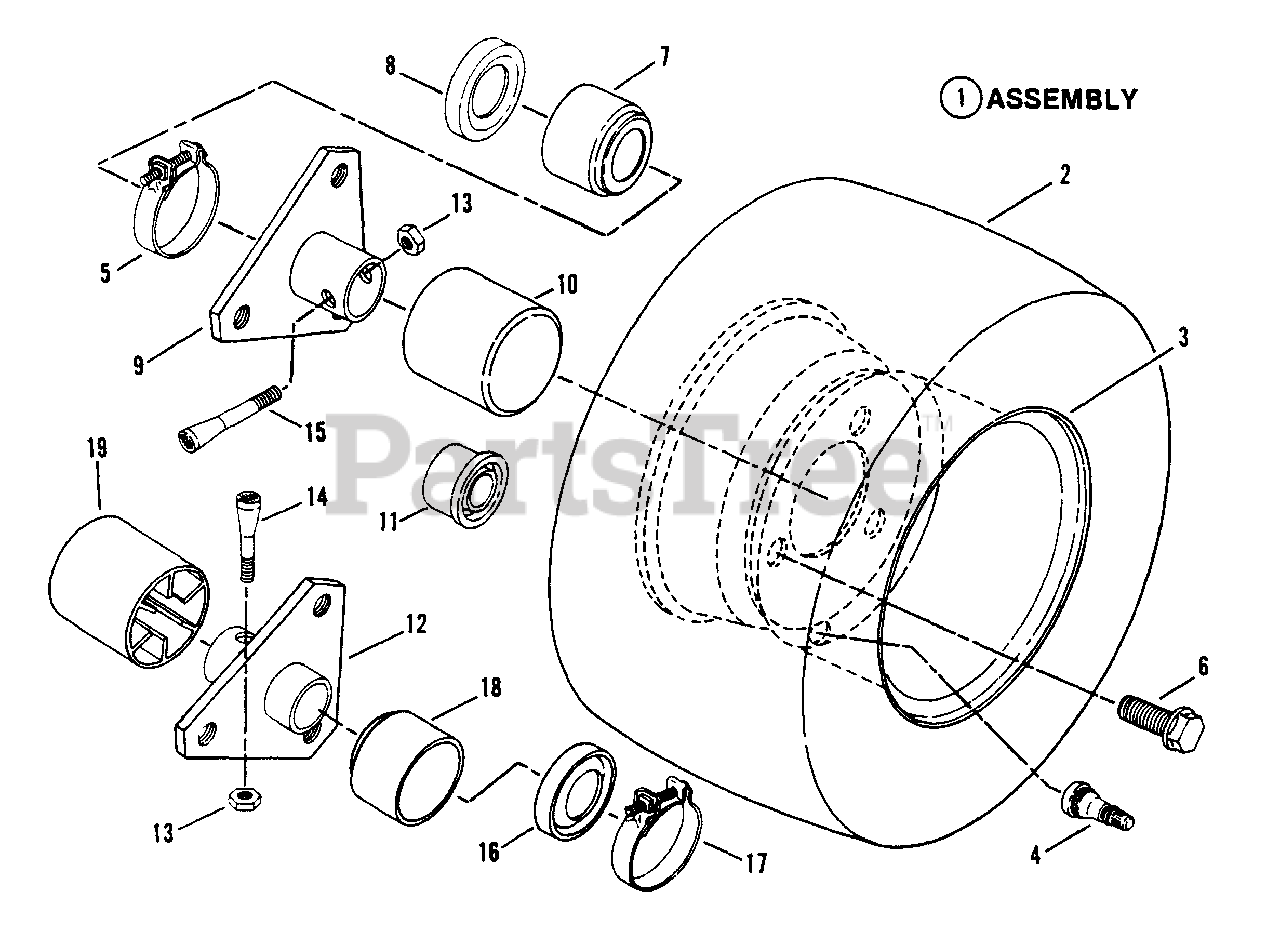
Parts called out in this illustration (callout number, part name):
1	ASSEMBLY, Rear Tire & Rim
2A	TIRE, Std, 16-4.80 x 8
2B	TIRE, Wide, 16-6.50 x 8
2C	TIRE, Ext Wide, 16-7.50 x 8
3A	RIM, Std, 16-4.80 x 8 Tire
3B	RIM, Wide,16-6.50 x 8 Tire
3C	RIM, Ext Wide, 16/7.50 x 8 Tire
4	VALVE, Air (Snap-in)
5	CLAMP, Right Hand
6	BOLT, 1/2-20 x 3/4" Lug
7	CAP, Seal RH 1.0" ID x 1.67" OD (8 & 10 HP)
8	SEAL, Oil
9	HUB, Wheel RH, 3 Hole 1" ID
10	CAP, Hub
11	CAP, Seal L.H. 3/4"
12	HUB, Wheel LH, 3 Hole 3/4" ID
13	NUT, 5/16-24 Hex Center Lock
14	BOLT, 5/16-24 x 1-5/8" Tapered Left Hand
15	BOLT, 5/16-24 x 2" Tapered Right Hand
16	SEAL, Oil Left Hand
17	CLAMP Left Hand
18	BOOT Left Hand
19	CAP, Hub Left Hand
